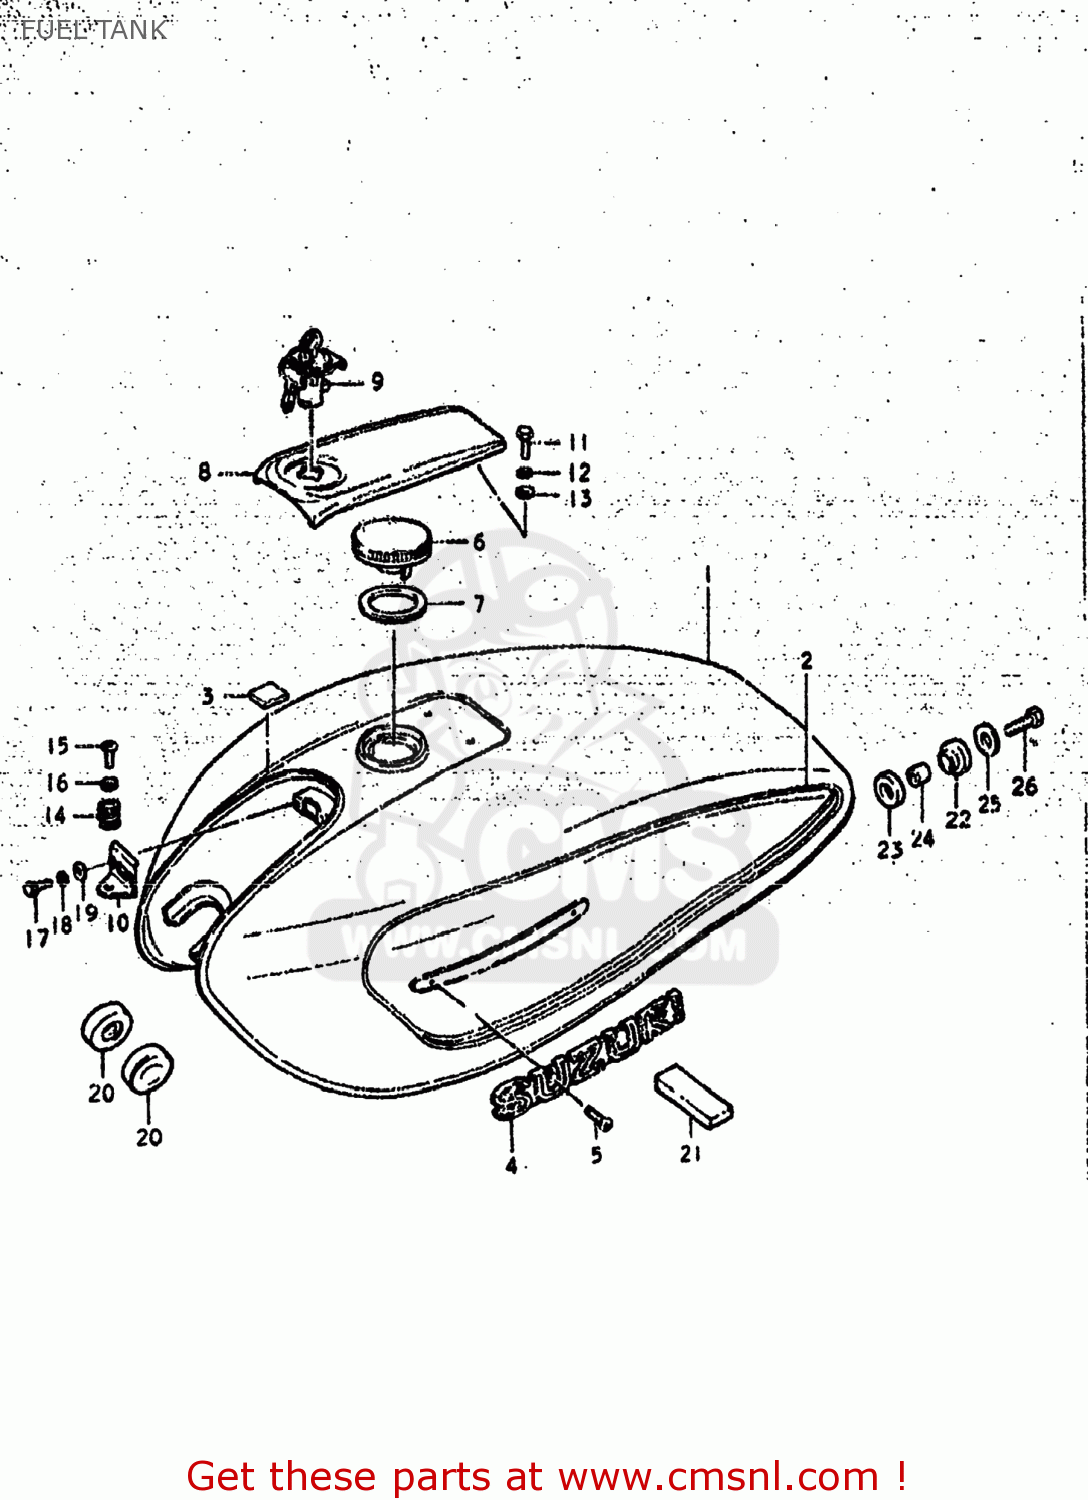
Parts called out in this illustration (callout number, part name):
1	TANK ASSEMBLY,FUEL
3	CUSHION,FUEL TANK FR COVER
4	EMBLEM
5	SCREW 3X6
6	CAP,FUEL TANK
7	GASKET (NAS)
8	COVER,FUEL TANK
9	LOCK,FUEL TANK FR COVER
10	HOLDER,FUEL TANK FRONT COVER
11	BOLT
12	LOCK WASHER
13	WASHER
14	SPRING
15	SCREW
16	LOCK WASHER
17	BOLT
18	LOCK WASHER
19	WASHER
20	CUSHION
21	CUSHION
22	CUSHION
23	CUSHION
24	SPACER(8.5X12X19)
25	WASHER
26	BOLT (8X30)
